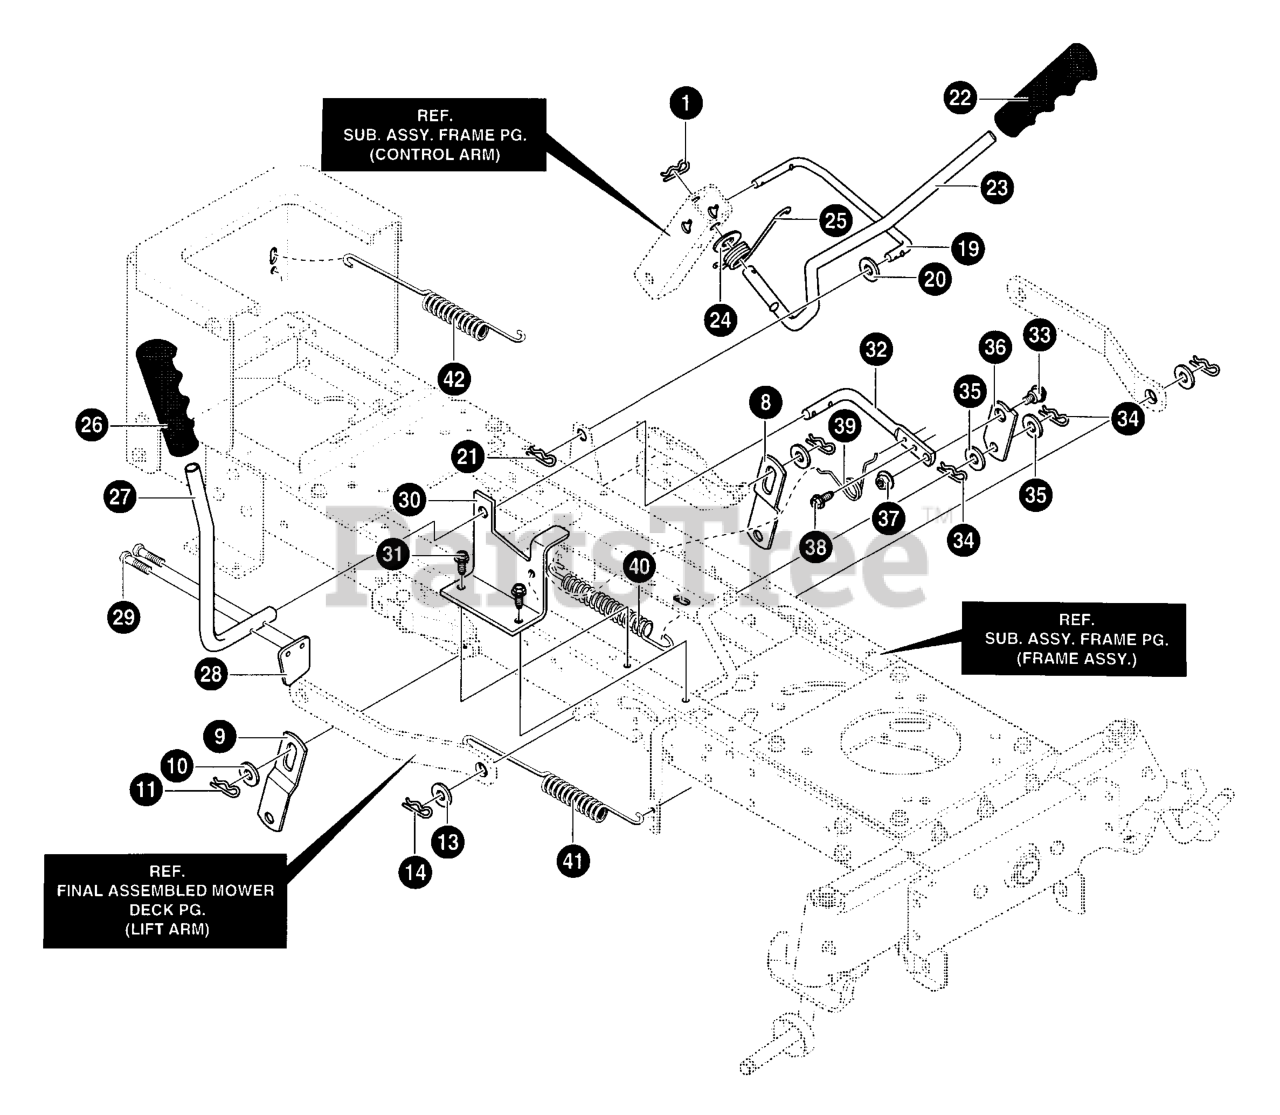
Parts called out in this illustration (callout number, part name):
1	HAIR PIN
8	LINK, LIFT LH
9	LINK- LIFT
10	FLATWASHER
11	PIN, HAIR
13	WASHER, FLAT
14	PIN, HAIR
19	LINK LIFT HANDLE
20	WASHER, FLAT
21	PIN, HAIR
22	GRIP, LIFT
23	HANDLE, LIFT
24	WASHER, FLAT
25	TORSION SPRING
26	Grip, PTO
27	PTO LEVER
28	PADDLE, SWITCH
29	Screw, Hex
30	BRACKET, PTO
31	BOLT, 5/16- 18X.5
32	LEVER, PTO
33	BOLT, .50X.75
34	PIN, HAIR
35	WASHER, FLAT
36	LINK PTO
37	NUT, 3/8- 16
38	SCREW, 5/16-18 x 0.75
39	TORSION SPRING
40	SPRING, TENSION
41	EXTENSION SPRING
42	EXTENSION SPRING
